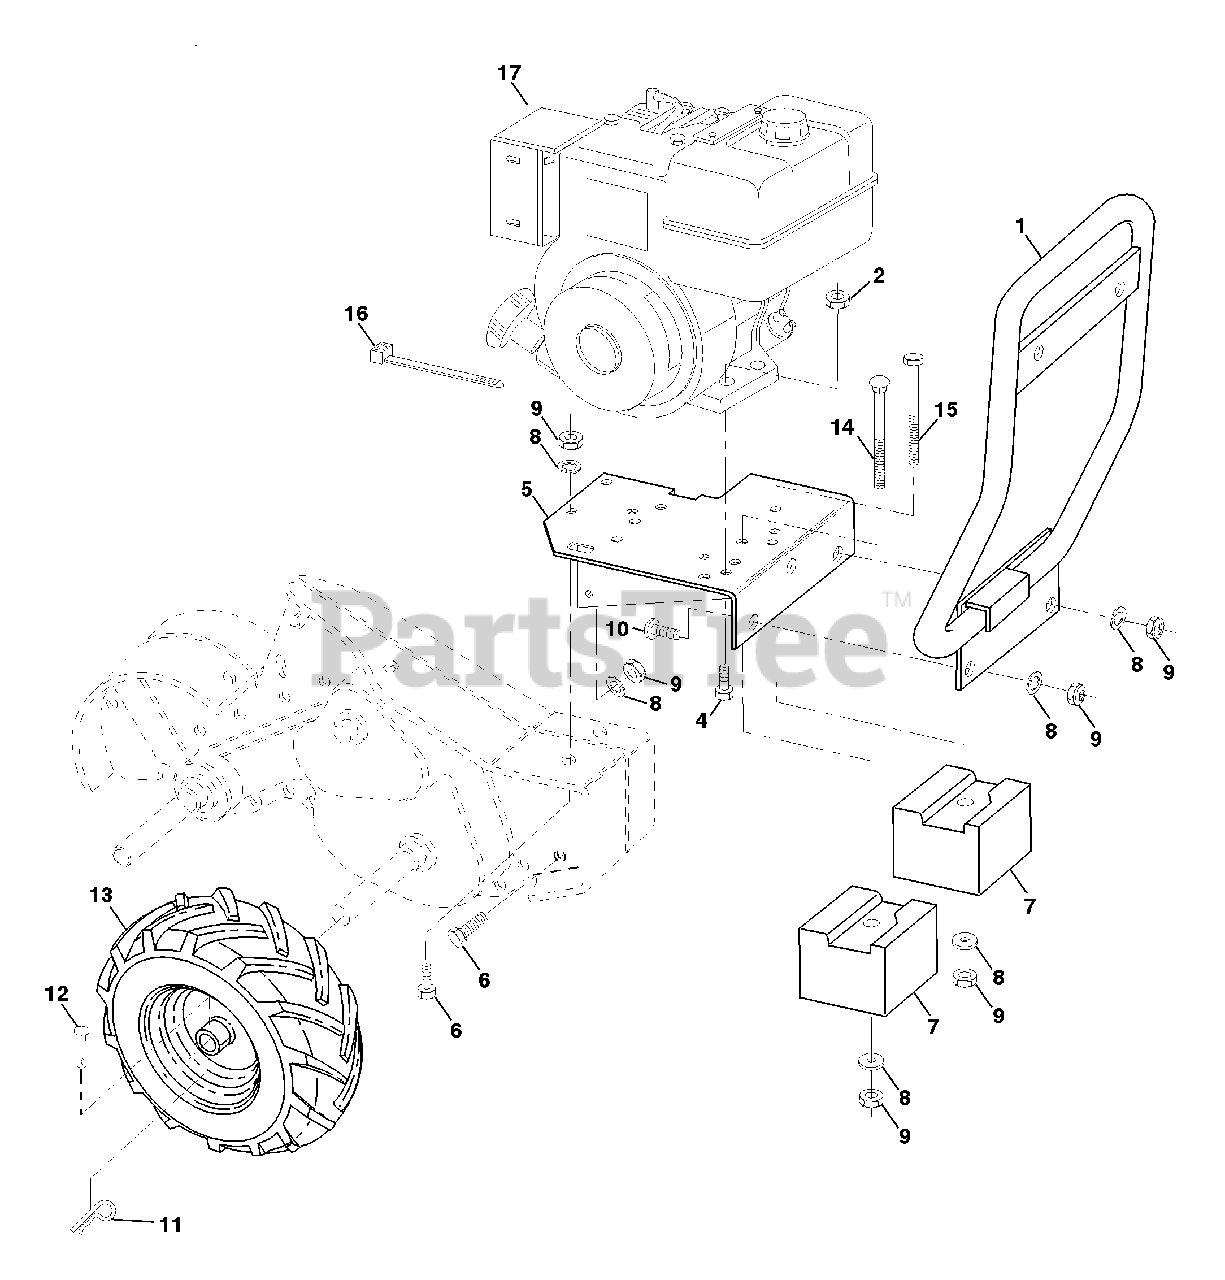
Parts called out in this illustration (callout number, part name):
2	Nut, Keps 5/16-18
4	Bolt, Hex 5/16-18 x 1-3/4
5	Bracket, Engine
6	Bolt, Hex Head 3/8-16 x 1
7	Counter Weight, R.H.
8	Washer, Lock 3/8
9	Nut, Hex 3/8-16
10	Bolt, Carriage 3/8-16 x 1
11	Clip, Hairpin
12	Rivet, Drilled
13	Rim
13	Tire Valve
14	Bolt, Carriage 3/8-16 x 4-1/2
15	Bolt, Hex Head 3/8-16 x 4-1/2
16	Tie, Cable
17	Engine
